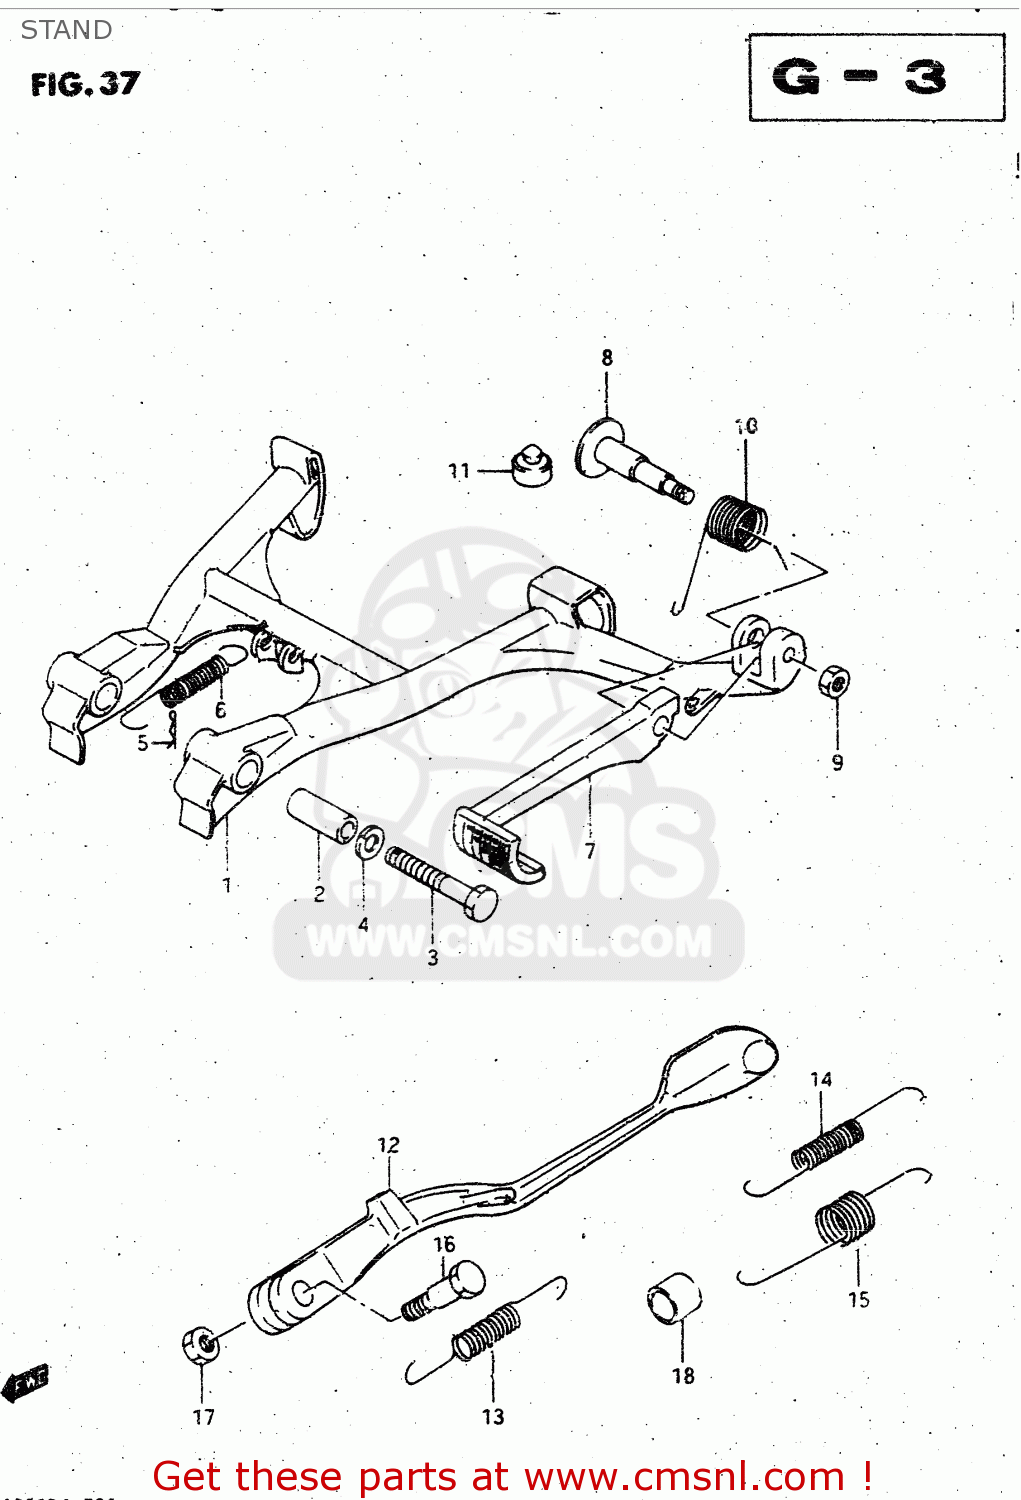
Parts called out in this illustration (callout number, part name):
1	STAND COMP,CENTER
2	SPACER(10X16X38.8)
3	BOLT 10X63
4	WASHER,LOCK,10
5	CLIP
6	SPRING
7	PEDAL COMP,CENTER STAND
8	BOLT COMP,CENTER STAND
9	NUT 8MM
10	SPRING
11	CUSHION
12	STAND,SIDE
13	SPRING
14	SPRING
15	SPRING
16	BOLT L:40
17	NUT
18	RUBBER, PROP STAND
